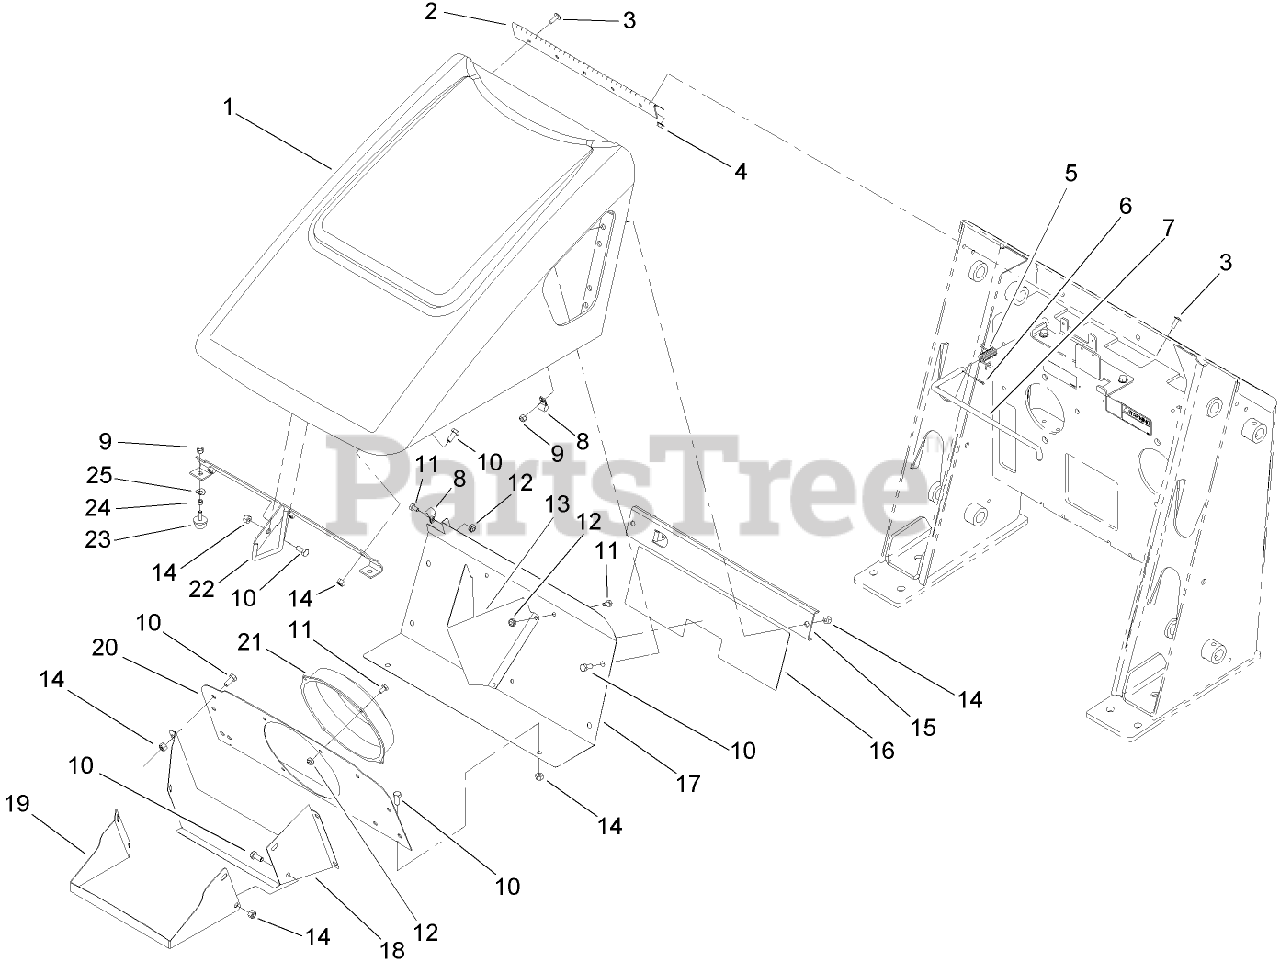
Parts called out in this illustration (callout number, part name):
1	Engine Hood ASM
2	HINGE-HOOD
3	SCREW-HEAD, TRUSS
4	NUT-HF
5	Spring-Torsion
6	PIN-COTTER
7	Rod-Support, Hood
8	CLAMP
9	NUT-LOCK, NI
10	SCREW-HH
11	SCREW-HH
12	NUT-LOCK, NI
13	BAFFLE-FAN
14	NUT-LOCK, NI
15	Bracket-Support, Hood
16	DECAL-SERVICE
17	Bracket-Fan, Back
18	Shroud-Fan
19	SHROUD-FAN, FRONT
20	Bracket-Baffle, Fan
22	ROD LATCH ASM
23	BUMPER
24	SPACER
25	WASHER-SPRING
